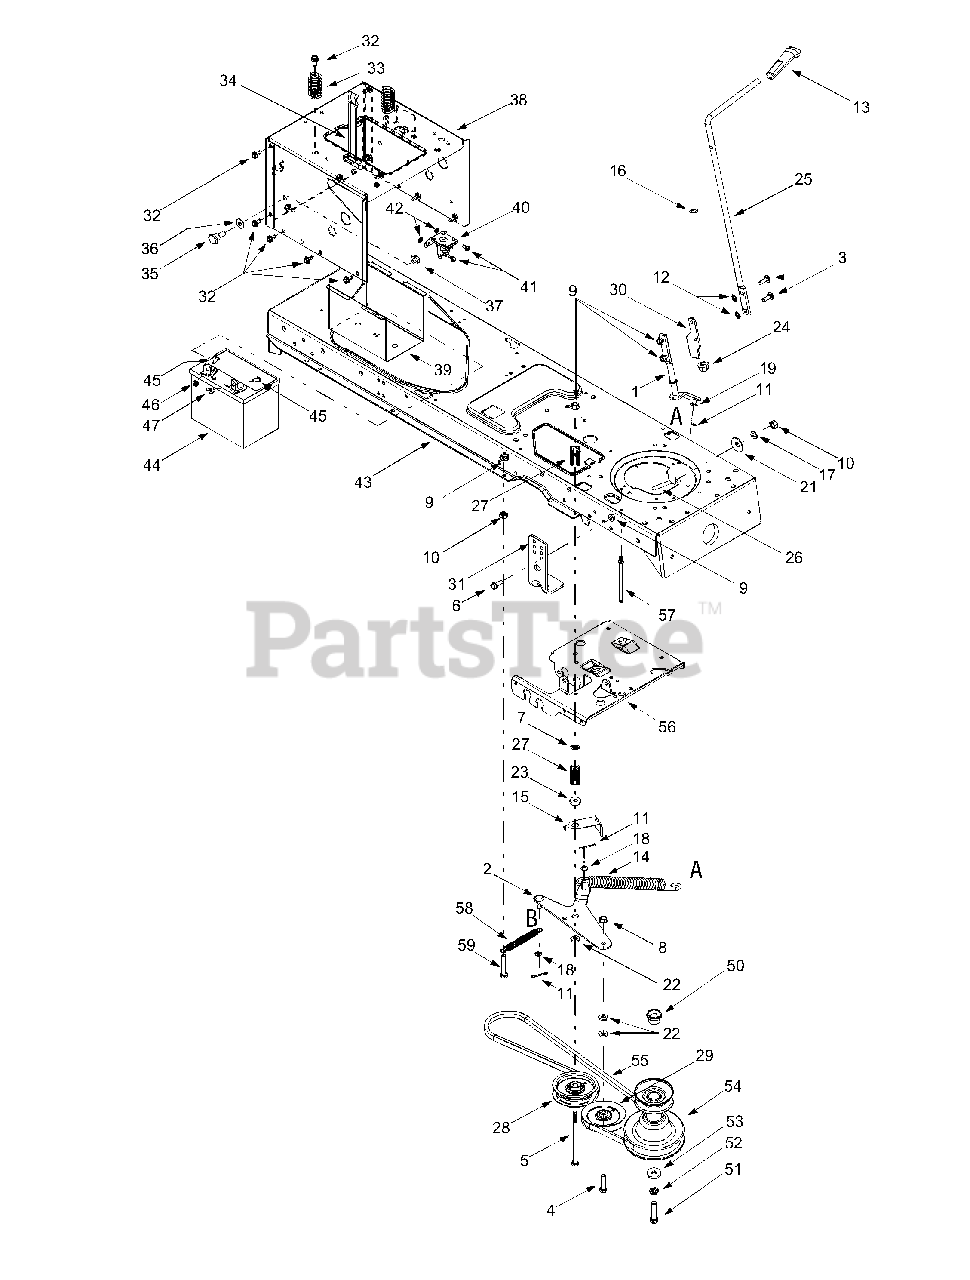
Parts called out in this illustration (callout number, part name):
1	PTO Engage Lever Assembly
4	Hex Cap Screw, 3/8-16 x 1.5
5	Hex Cap Screw, 3/8-16 x 5.5
6	Hex Head Washer Screw, 5/16-18 x .875
7	Push Nut, 3/8
8	Flange Lock Nut, 3/8-16
9	Flange Lock Nut, 5/16-18
10	Hex Nut, 5/16-18
11	Cotter Pin, 1/8 x 1.25
12	Speed Nut, .3125
13	PTO Knob
14	Extension Spring, .75 x 6.75
16	Flat Washer, .510 x .750 x .033
17	Lock Washer, 5/16
18	Flat Washer, .385 x .62 x .063
19	Flat Washer, 5/16
21	Bell Washer, .39 x 1.13 x .062
22	Flat Washer, .407 x .812 x .135
23	Shoulder Spacer, .380
24	Hex Split Flange Bearing, .5
26	Belt Keeper Rod
27	Spacer, 3/8 x 1.54
28	Idler Pulley, 3.5
29	Idler Pulley, 4.0
32	Self Tapping Screw, 5/16-18 x .625
33	Compression Spring, 1.28 x 3.5
34	Battery Strap
35	Shoulder Screw, .625 x .5, 7/16-20
36	Bell Washer, .45 x 1.0 x .062
37	Flange Lock Nut, 7/16-20
41	Self Tapping Screw, 1/4-20 x .5
42	Lock Washer, 1/4
45	Hex Cap Screw, 1/4-20 x .62
46	Hex Sems Nut, 1/4-20
47	Wing Nut, 1/4-20
50	Spacer Cup
51	Hex Head Cap Screw, 7/16-20 x 1.25
52	Lock Washer, 7/16
53	Flat Washer, .450 x 1.25
54	Engine Pulley, 3.56 OD x 5.56
55	PTO Belt
57	Keeper Pin, 5/16 x 4.75
58	Extension Spring, .50 x 5.0
59	Hex Cap Screw, 5/16-18 x 1.75
